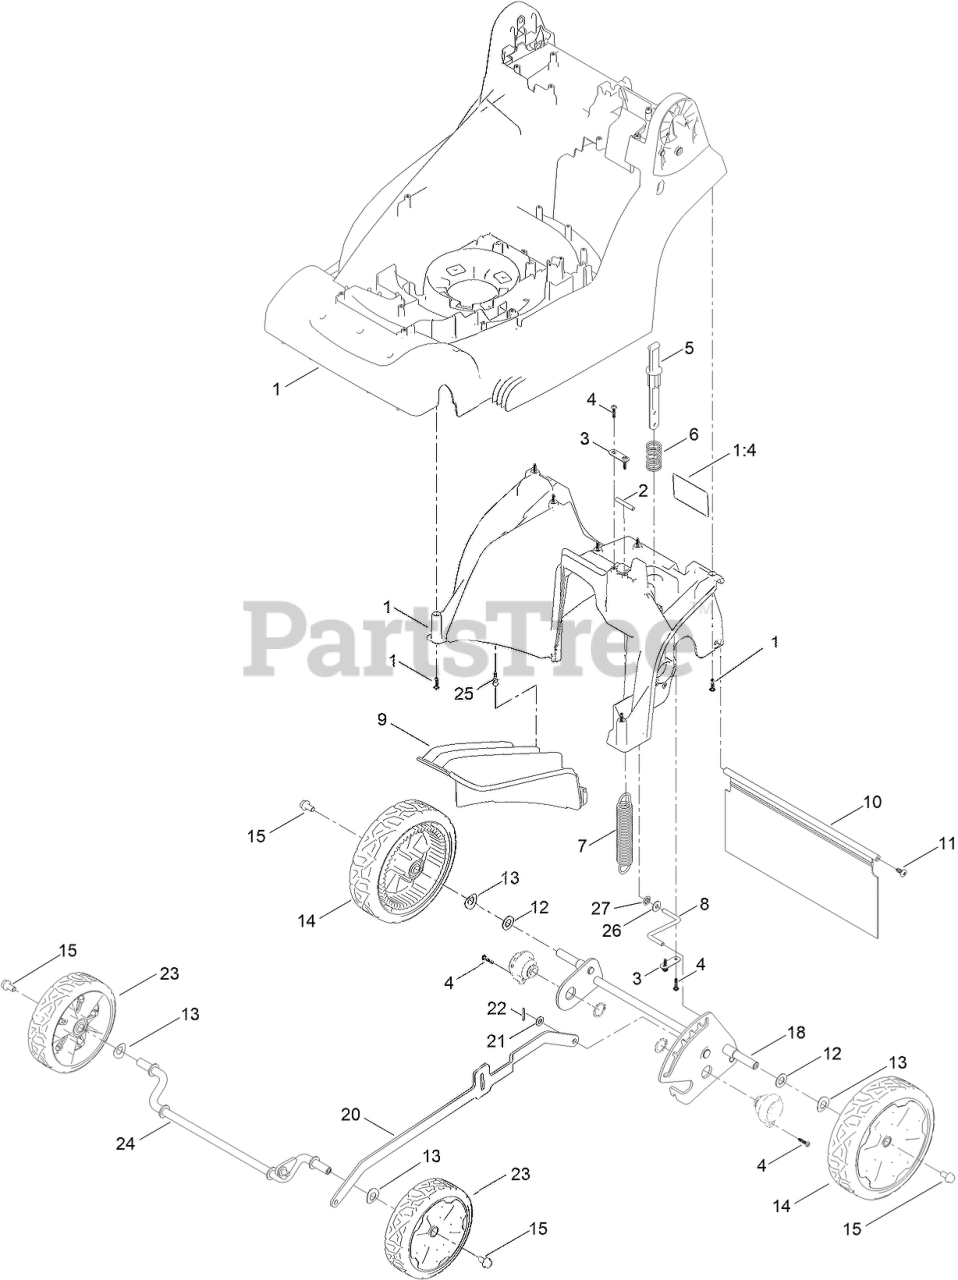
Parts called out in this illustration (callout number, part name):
1	DECK, GLUED (43)
1:4	DECAL - SAFETY
2	BAR, SPRING MOUNT
3	AXLE PLATE, SMALL
5	HOC BUTTON PLUNGER
6	SPRING, HOC BUTTON
7	HOC SPRING, 4 WHEEL
8	HOC WIRE
9	MULCH PLUG
10	SHIELD-TRAILING
11	SCREW-PTH
12	WASHER-PLAIN
13	WAVE WASHER, FRONT WHEELS
14	WHEEL-REAR ASSEMBLY
15	BOLT, M8 X 1.25, 16MM
18	REAR AXLE FRAME, ASSY, WHEEL
20	Cover, Exhaust-Right
21	WASHER-PLAIN
22	COTTER PIN
23	WHEEL-TORO FRONT ASSEMBLY
24	FRONT AXLE, ASSEMBLY
25	PIN, RETAINING, MULCH PLUG
26	WASHER
27	WASHER
